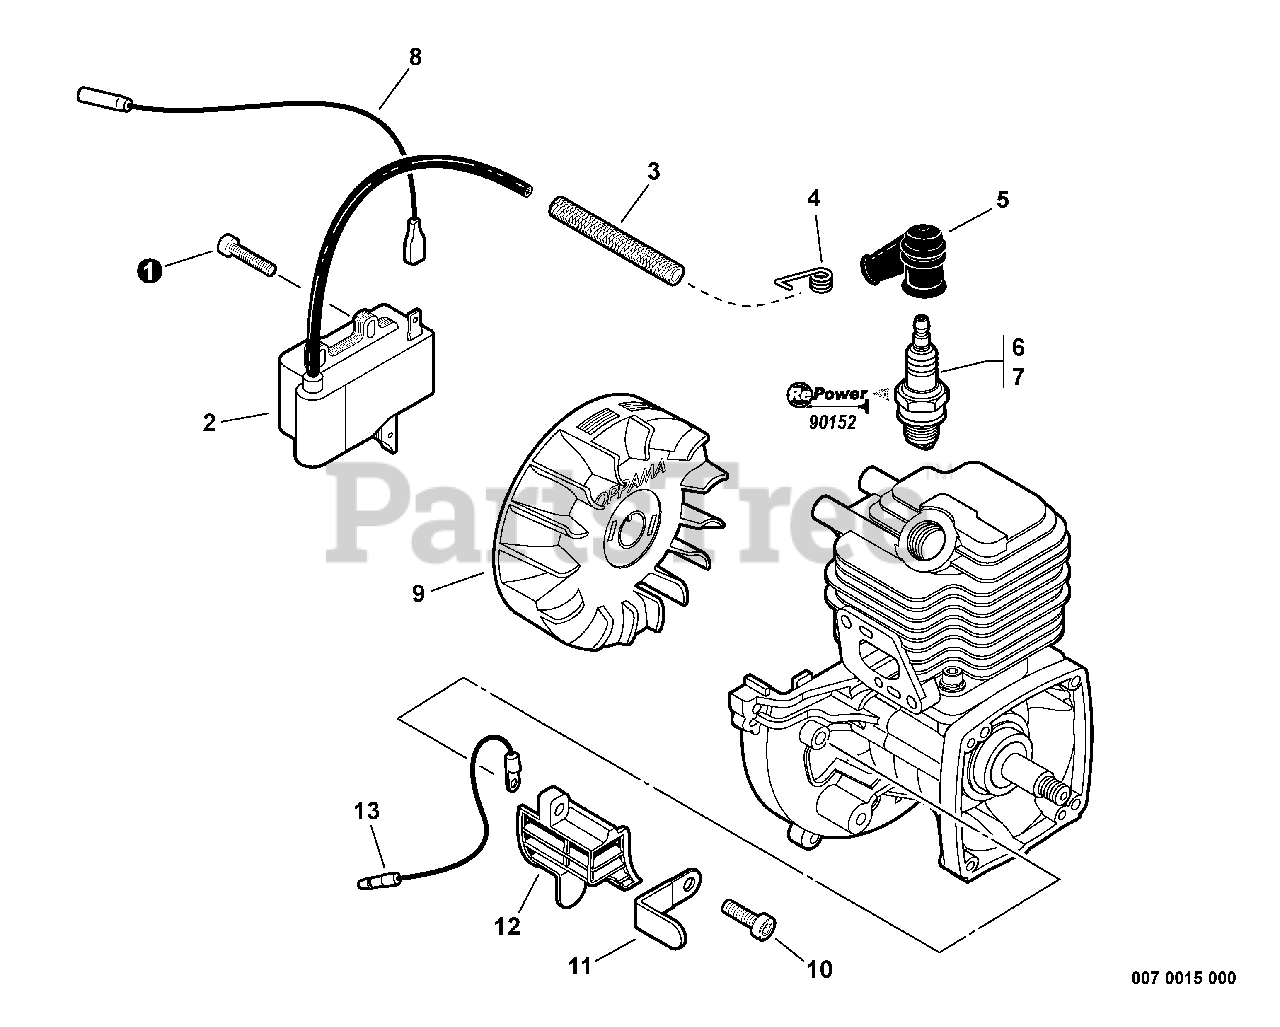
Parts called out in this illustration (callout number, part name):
1	BOLT, TORX 4×20
2	COIL, IGNITION
3	TUBE, INSULATOR 7×8.6×65
4	TERMINAL, SPARK PLUG
5	CAP, SPARK PLUG
6	SPARK PLUG - BPM8Y
7	SPARK PLUG - BPMR8Y
8	LEAD - IGNITION L= 210
9	FLYWHEEL
10	BOLT, TORX 5×16
12	COVER, DUST
13	LEAD - GROUND L= 115
14	TUNE-UP KIT - REPOWER
